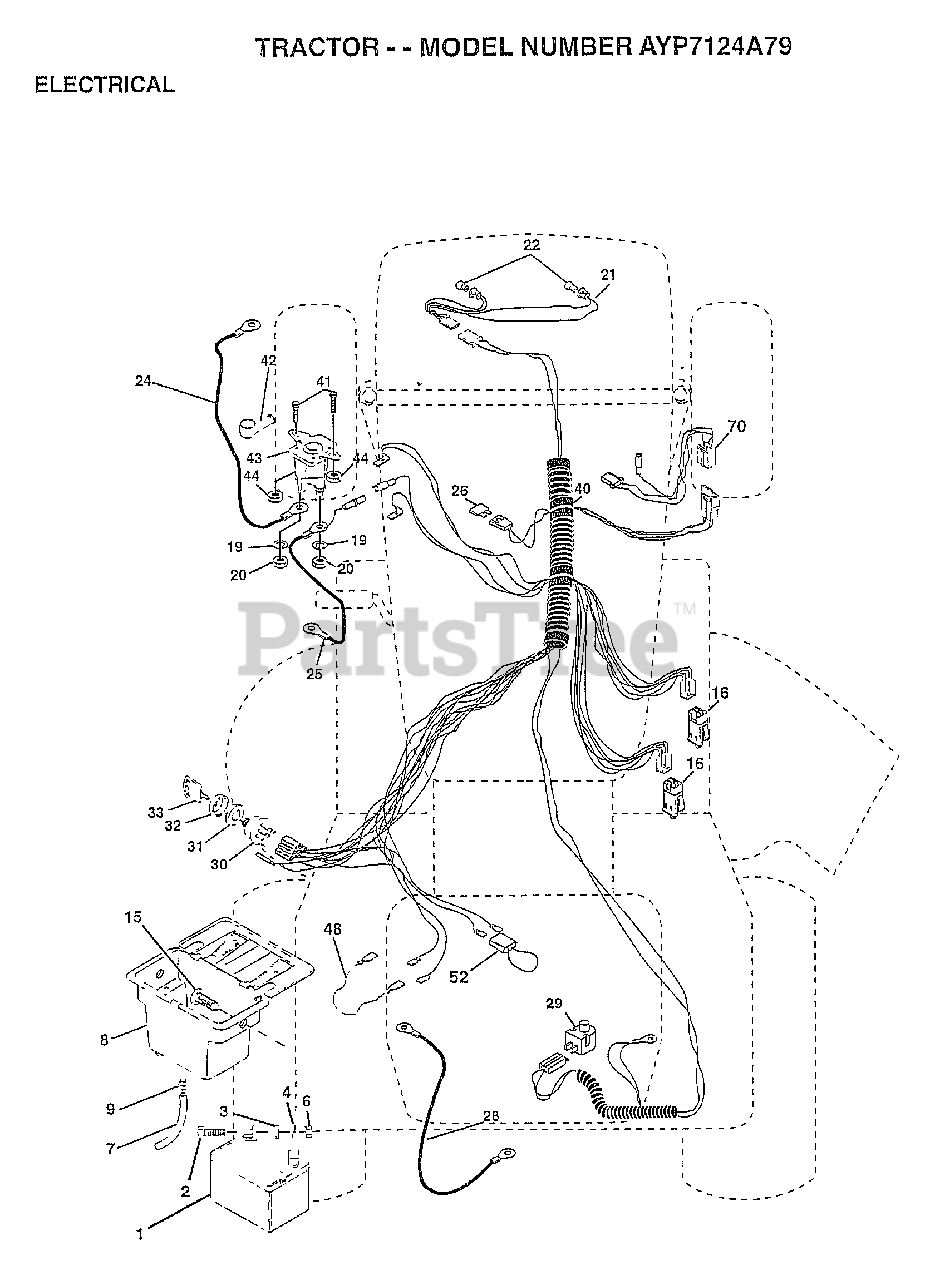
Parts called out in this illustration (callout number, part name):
2	BOLT LT
3	WASHER
4	LOCKWASHER
7	TUBE T
8	"CASE,BATTERY.MECH"
9	HOSE CLAMP T
15	FASTNER.SNAP-IN
16	SWITCH INTERLOCK
20	NUT
21	"HARNESS,LIGHT SOC"
22	HEADLAMP BULB
24	"CABLE T, BATTERY"
25	CABLE.BTRY.6GA.RD
26	FUSE HYT
28	CABLE T
29	SWITCH SEAT
30	SWITCH IGN 4POS
31	NUT IGNITION
32	COVER KEY SWITCH
33	KEY
40	HARNESS-IGNITION
41	BOLT HXHD FIN
44	NUT HXKEP 1/4X20
48	ADAPTER AMMETER
52	PROTECTION LOOP
70	HARNESS ENG DUAL
